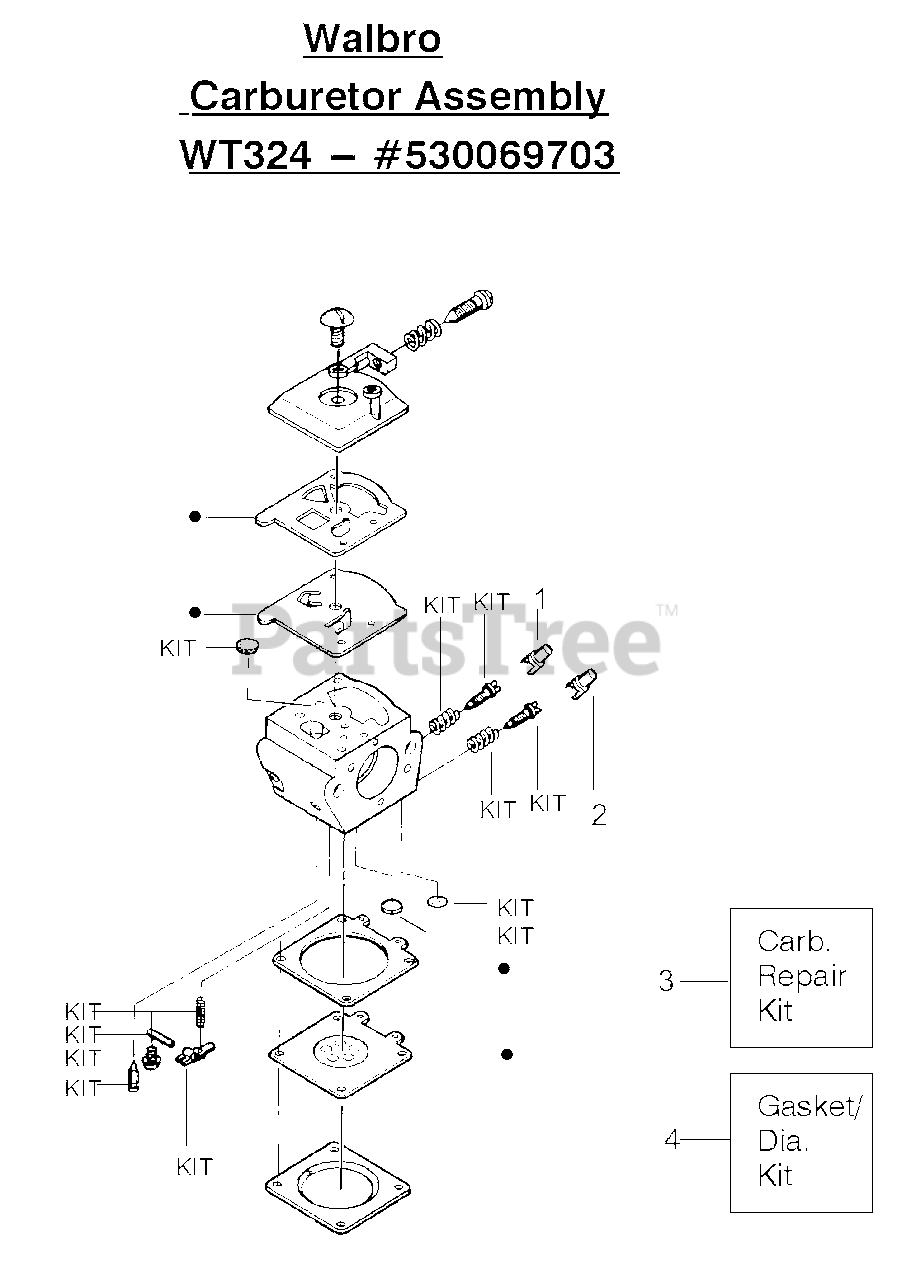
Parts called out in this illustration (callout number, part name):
1	Limiter Cap-High (brown)
2	Limiter Cap-Low (tan)
3	Carburetor Repair Kit Walbro (WT324)
4	Gasket Diaphragm Kit Walbro (WT324)
530069703	Carburetor Assembly WT324
